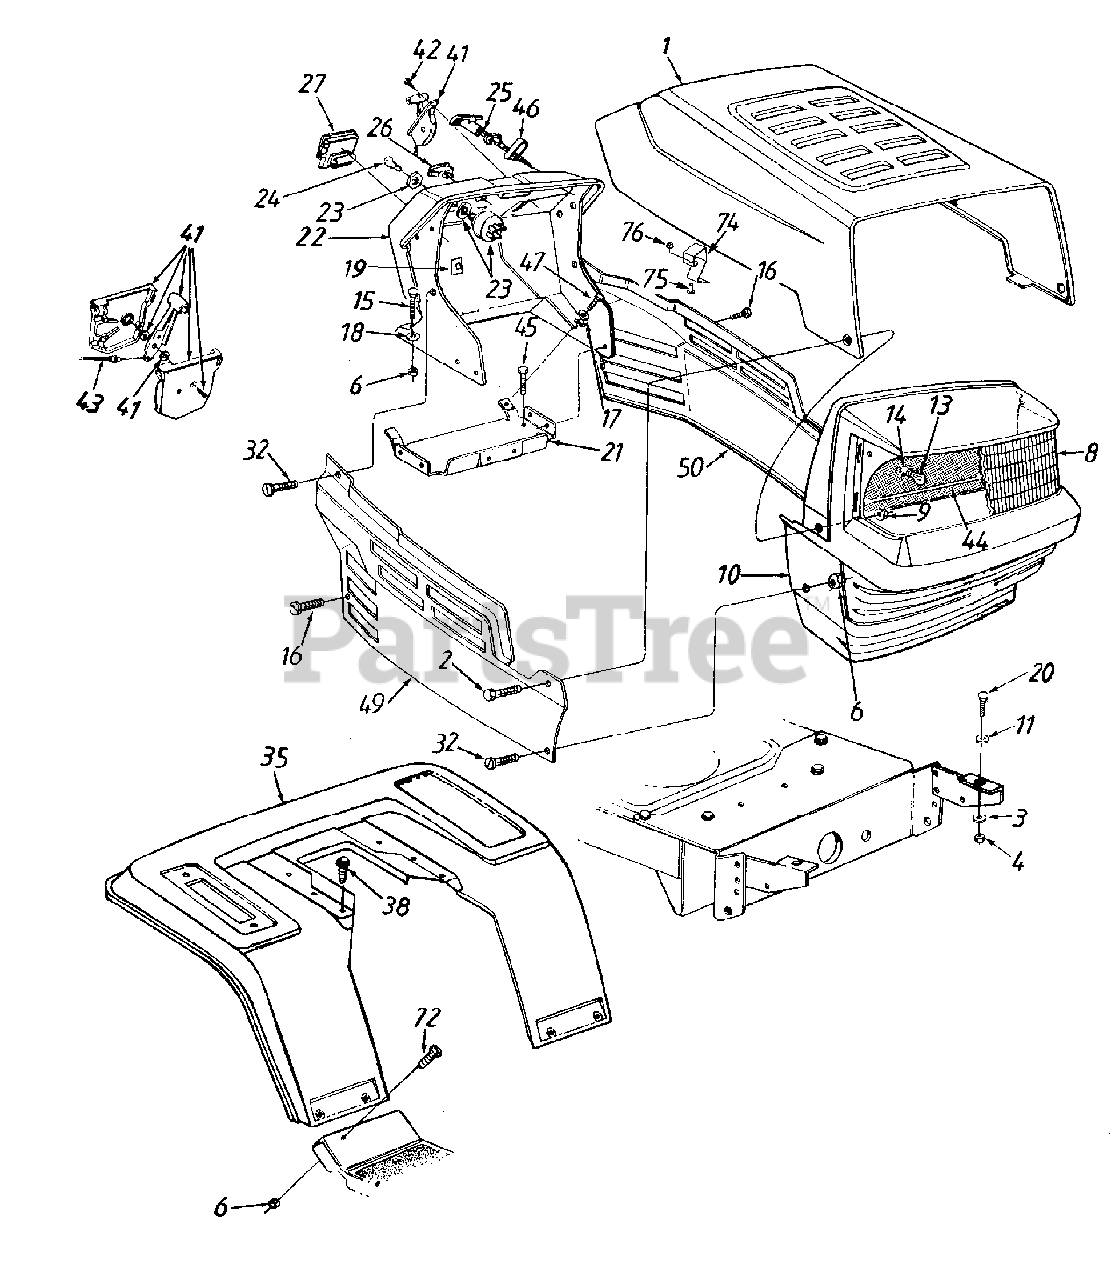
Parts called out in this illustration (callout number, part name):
3	L-Wash. 5/16" I.D.
4	Hex Nut 5/16-18 Thd.
6	Hex Sems Nut 1/4-20 Thd.
8	Headlight Lens w/o Logo
8	Headlight Lens w/ Logo
9	Flange L-Nut 1/4-20 Thd.
10	Grille
11	Fl-Wash. .344" I.D. x 1" O.D.
12	Hex Nut 5/16-18 Thd.
14	Socket
15	Carriage Bolt 1/4-20 x .75" Lg.
16	Hex Wash. Hd. TT-Tap Scr.1/4-20 x .5" Lg.
17	Fl-Wash. .281" I.D. x .73" O.D.
18	Bolt Retainer 1/4" I.D.
19	Speed Nut 1/4-20 Thd.
20	Hex Bolt 5/16-18 x .75" Lg. (Gr.5)
21	Gas Tank Support Brkt.
22	Dash w/Ammeter Hole
22	Dash w/o Ammeter Hole
23	Ignition Switch (6 PIN)
23	Ignition Switch (5 PIN)
24	Ignition Key
25	Choke Control 23" Lg.
25	Choke Control 38" Lg.
25	Choke Control 29" Lg.
25	Choke Control 20" Lg.
26	Light Switch
27	Ammeter
32	Pan Hd. Scr. 1/4-20 x .75" Lg.
41	Throttle Box Ass'y.
42	Truss Mach. AB-Tap Scr.#10 x .5" Lg.
43	Throttle Control Wire 18.5" Lg.
43	Throttle Control Wire 35" Lg.
43	Throttle Control Wire 22" Lg.
44	Grille Reflector Label
45	Hex Wash. Hd. B-Tap Scr.5/16-18 x .5" Lg.
46	Choke Retainer
47	Hex TT-Tap Scr. 1/4-20 x .75" Lg.
73	Fl-Wash. .283" I.D. x .75" Lg.
74	Hood Latch
75	Hex Sems Nut 10-24 Thd.
76	Truss Mach. Scr. 10-24 x .5" Lg.
